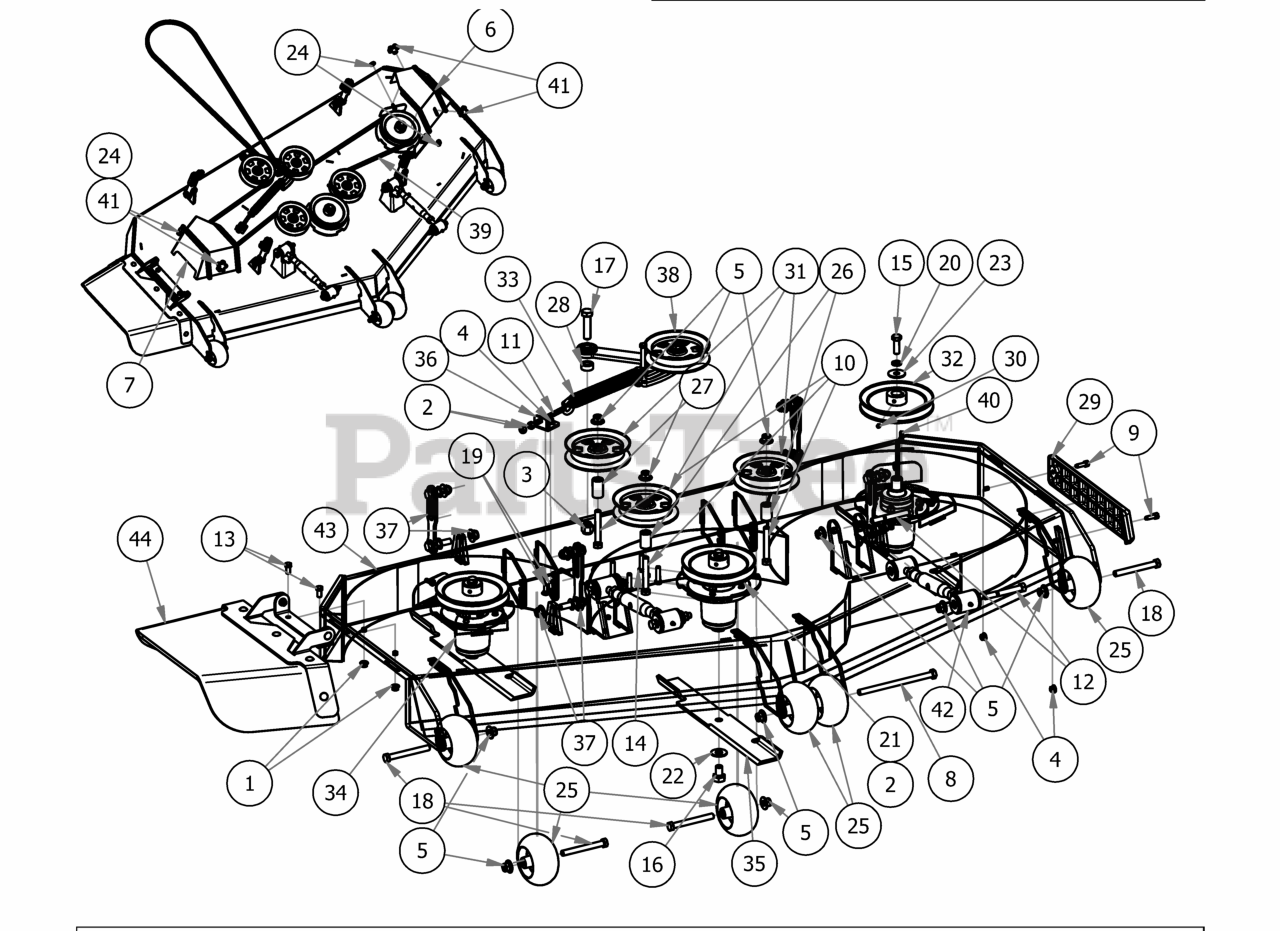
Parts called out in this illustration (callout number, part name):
1	3/8" Flange Nut
2	3/8" Hex Nut
3	5/8 Std NC Nylock Nut
4	5/16" Nylon Flange Nut
5	1/2-13 Nylon Flange Nut
6	2019 72" Left Outlaw Gen2 Pulley Cover
7	2019 72" Right Outlaw Gen2 Pulley Cover
8	1/2-13 x 8 Hex Bolt Grade 5
9	5/16-18 x 1 GR 5 Hex Bolt Zinc
10	1/2 x 3 1/2 Flange Bolt Grade 8
11	4" 3/8-16 Eye Bolt
12	1/2" x 4" Bolt (Grade 8)
13	3/8" x 3/4" Hex Bolt
14	3/8 x 1.5" Bolt
15	1/2"-20 x 1 1/2 - Grade 5 Fine Thread Bolt
16	5/8" x 1 1/2" Grade 8 Hex Bolt (Fine)
17	5/8" x 2 1/2" Grade 5 Hex Bolt (Coarse)
18	1/2" x 4 1/2" Bolt
19	5/16" x 7/8" Carriage Bolt
20	1/2" Lock Washer
21	3/8" Lock Washer
22	5/8'' Flat Washer
23	1/2" Belleville Washer
24	.360 ID Plastic Washer-Black
25	2019 Deck Wheel
26	.502 ID X .750 OD X 1.500 Long Spacer
27	1 3/4" Pulley Spacer
28	5/8" x 1/" Collar W/One Set Screw
29	REVISED TRIM BUMPER_20180226
30	5/16 Set Screw
31	5-3/4 Idler Pulley
32	7" Deck Pulley
33	2019 Outlaw Gen2 Deck Spring
34	OUTLAW SPINDLE ASSEMBLY
35	72" High Lift Fusion Blade
36	2019 Deck Eye Bolt Tab
37	Deck Hangar Assembly
38	2019 Renegade Deck Idler
39	Belt for 72" Renegade
40	1/4" x 1" Key
41	5/16" Knob
42	Turnbuckle
43	2019 Sloped 72" Deck
44	2019 Outlaw Gen2 Chute Assembly
